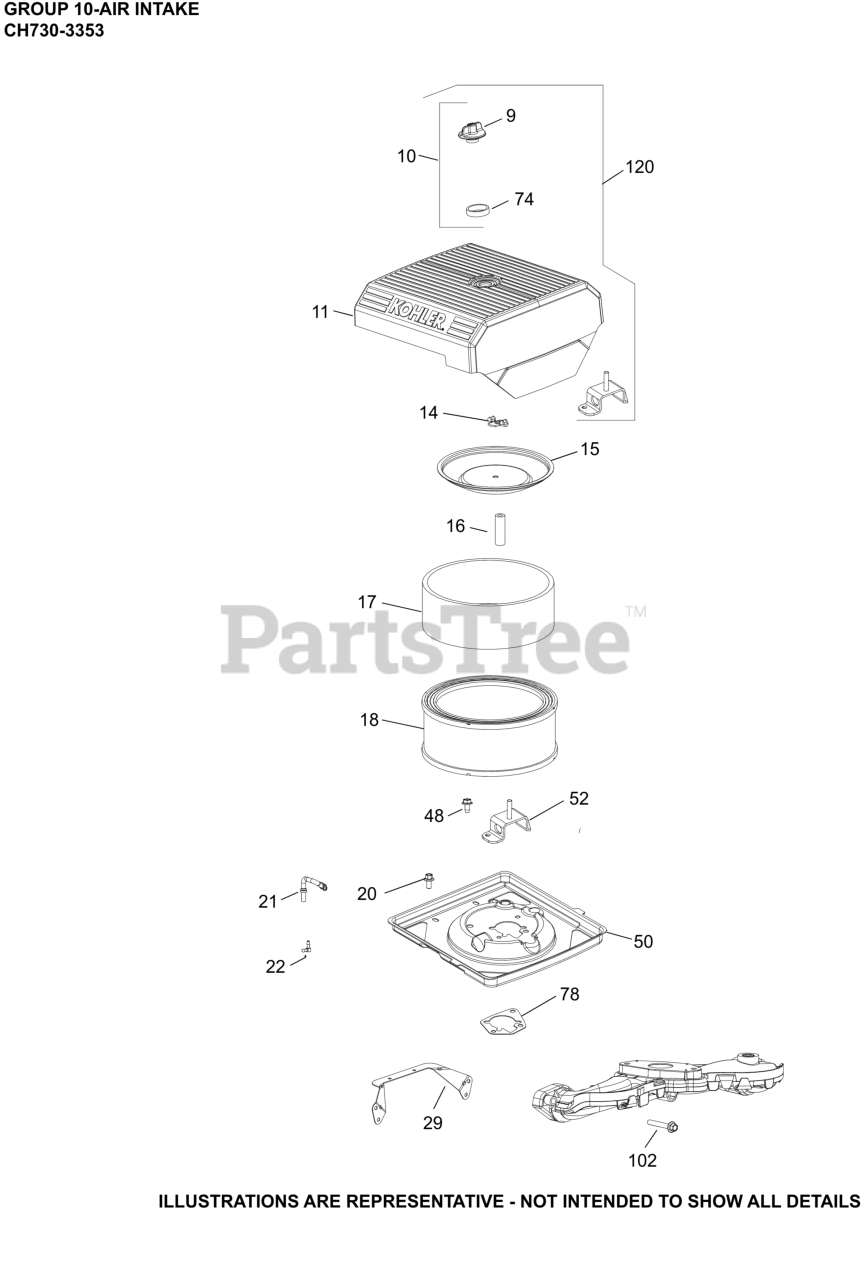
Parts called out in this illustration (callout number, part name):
9	KNOB, COVER
10	KIT, KNOB W/SEAL
11	COVER, AIR CLEANER
14	NUT, WING
15	COVER, INNER AIR CLEANER
16	SEAL BREATHER
17	PRE-CLEANER (HIGH)
18	AIR FILTER ELEMENT
20	SCREW, FLG THD FRM M6X1.0X16
21	HOSE, EVAP
22	CONNECTOR, EVAPORATIVE HOSE
29	AIR CLEANER BRACKET
48	SCREW, THREAD FORMING
50	KIT, AIR CLEANER BASE
52	BRACKET, AIR CLEANER
78	GASKET, AIR CLEANER BASE
102	SCREW, FLG M6X1.0X40
120	KIT, AIR CLEANER COVER
